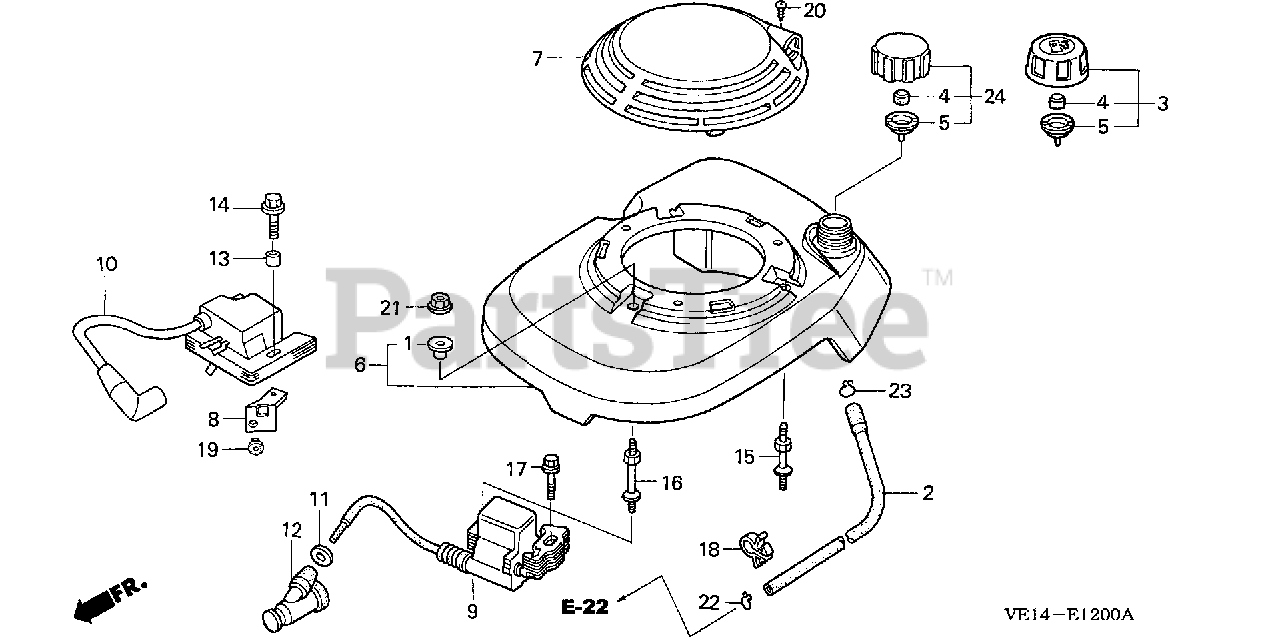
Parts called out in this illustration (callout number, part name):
1	COLLAR, AIR CLEANER (TOYO ROKI)
2	TUBE, FUEL TANK (135MM)
3	CAP ASSY., FUEL TANK
4	SPONGE, FUEL CAP BREATHER
5	GASKET, FUEL CAP
6	COVER, FAN
7	HOOD, FAN COVER *R8* (SMOOTH) (BRIGHT RED)
8	GUIDE, FAN COVER
10	COIL ASSY., IGNITION
13	COLLAR, ROTO-STOP
14	BOLT, FLANGE (6X32) (CT200)
15	BOLT, STUD (BRAKE)
16	BOLT C, STUD
18	CLIP B, CABLE (9MM BLACK)
19	GROMMET, DEFOGGER CORD (15MM)
20	SCREW, TAPPING (4X20)
21	NUT, FLANGE (6MM)
22	CLIP, TUBE (B8)
22	CLIP, TUBE (B10)
23	CLIP, TUBE (B10)
